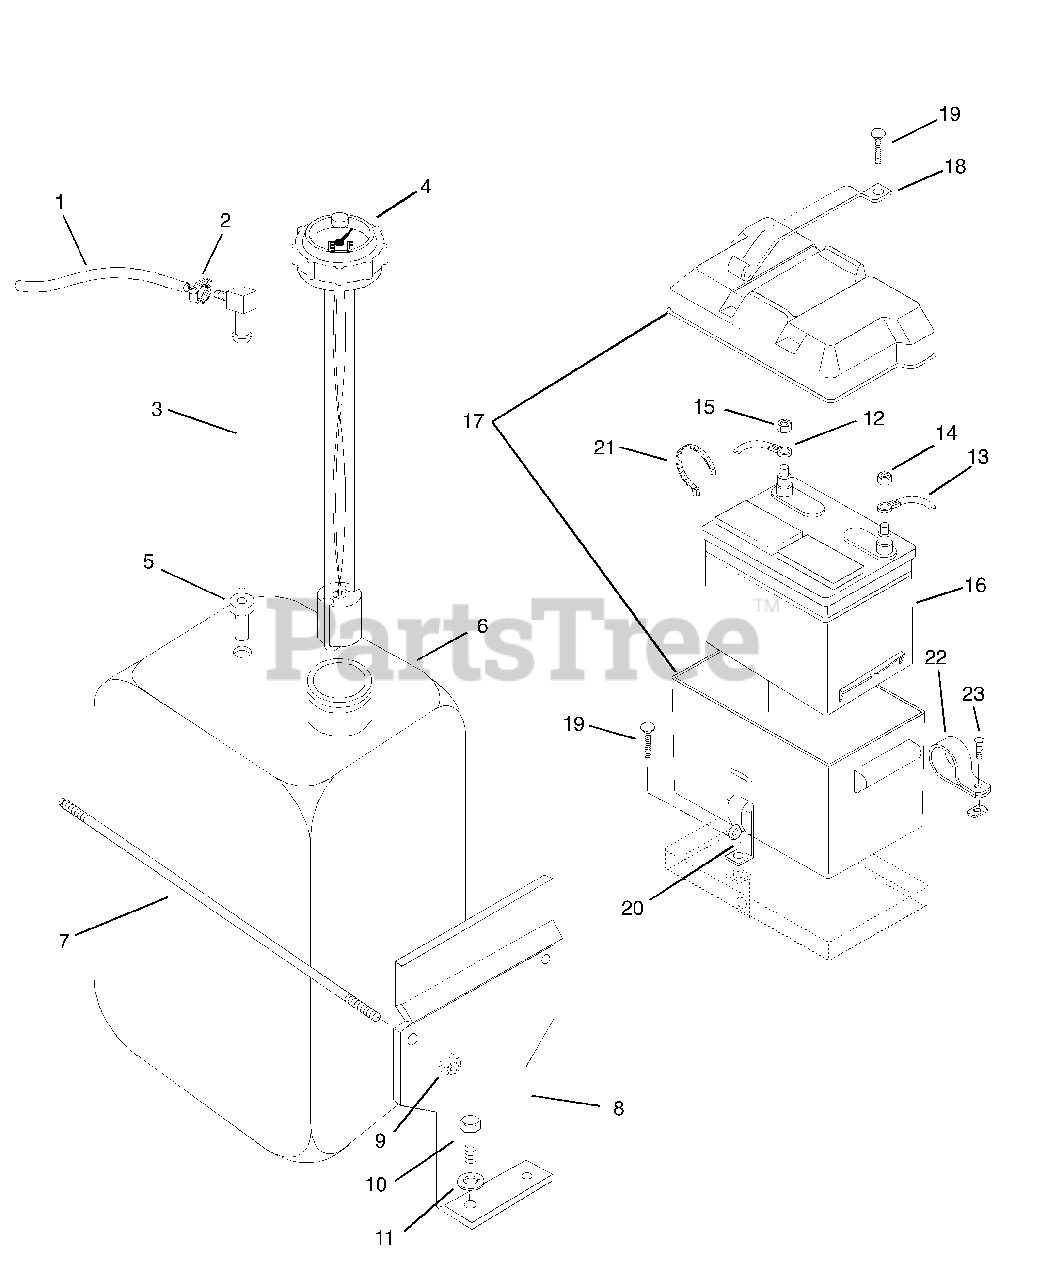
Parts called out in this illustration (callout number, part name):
1	Gas Line - Bulk 1/4 IN. Inner Diameter
2	Hose Clamp
3	Fitting, Tank
4	Gauge, Fuel
6	Tank, Fuel
7	Rod, Tank
8	Weldment, Tank Bracket
9	Nut-Locking-Center .31-18
10	Bolt-Hex .31-18 x .50 Grade 5
11	Washer-Locking .31 x .078
12	Negative Battery Cable
13	Positive Battery Cable
14	Nut-Hex .31-18
15	Nut-Hex .38-16
16	Battery, Marine Type
17	Battery Box
18	Strap-Battery Hold-Down
19	Bolt-Round Head Square Neck .31-18 x 1.75 Grade 5
20	Latch Assembly - Battery Hold-Down
21	Tie Wrap
22	Clamp-Steel 1.0
23	Bolt-Hex .38-16 x .75 Grade 5
